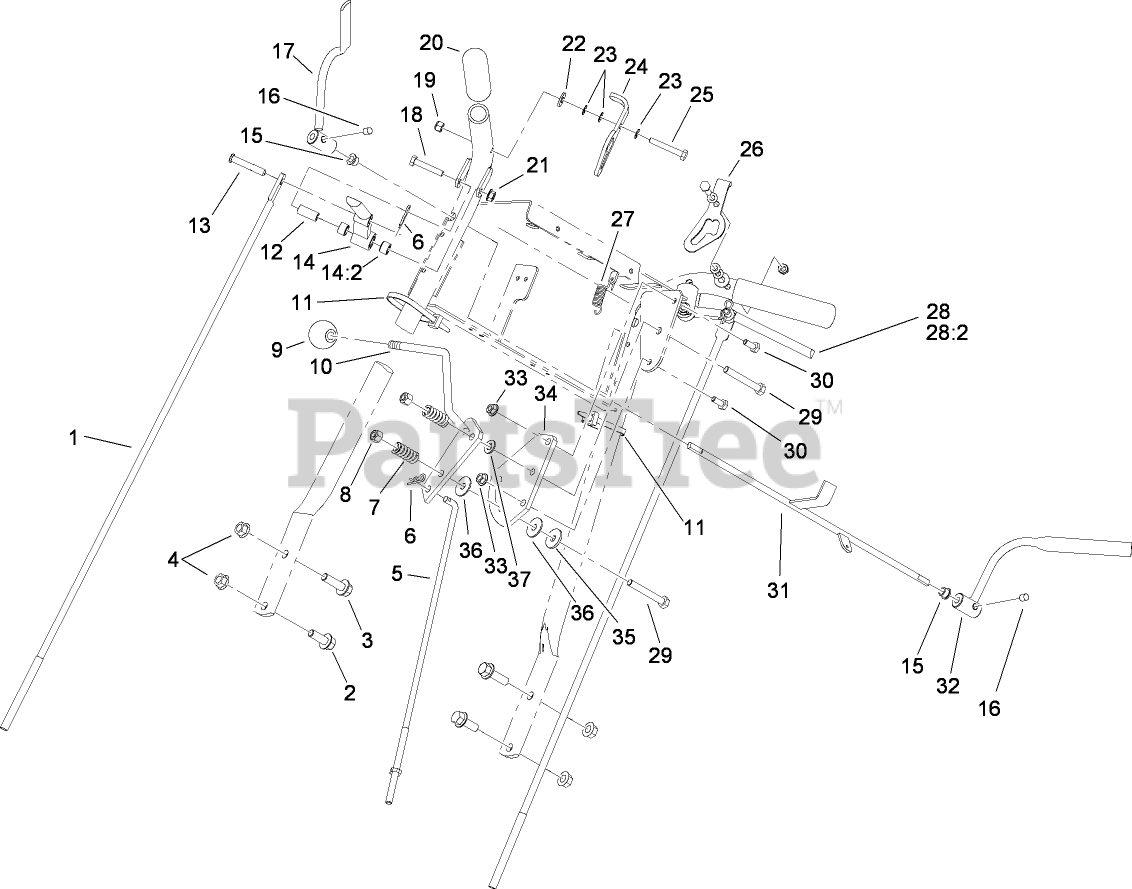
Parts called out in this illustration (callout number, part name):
1	ROD-LEVER, DRIVE
2	SCREW-HHF
3	SCREW-HHF
4	NUT-HF
5	ROD-CONTROL, SPEED
6	PIN-COTTER
7	SPRING-COMPRESSION
8	NUT-LOCK, NI
10	LEVER-SHIFT
11	TIE-CABLE
12	Bushing-Lever, Drive
13	Pin-Clevis
14	LH Drive Lever ASM
14:2	BUSHING-SLEEVE
15	BUSHING-NYLON
16	SCREW-SET
17	LH OPERATOR PRESENCE CONTROL LEVER ASM
18	SCREW-HH
19	NUT-LOCK, NI
20	GRIP-FOAM
21	NUT-HF
22	WASHER-FLAT
23	WASHER-SPRING
24	LATCH-THUMB, LH
25	SCREW-HH
26	LATCH-THUMB, RH
27	SPRING-EXTENSION
28	RH Drive Lever ASM
28:2	BUSHING-SLEEVE
29	SCREW-HH
30	SCREW-HH
31	ROD ASM
32	RH OPERATOR PRESENCE CONTROL LEVER ASM
33	NUT-HF
34	PLATE-LEVER, SHIFTER
35	Washer-Friction
36	Washer-Friction
37	WASHER-PLAIN
